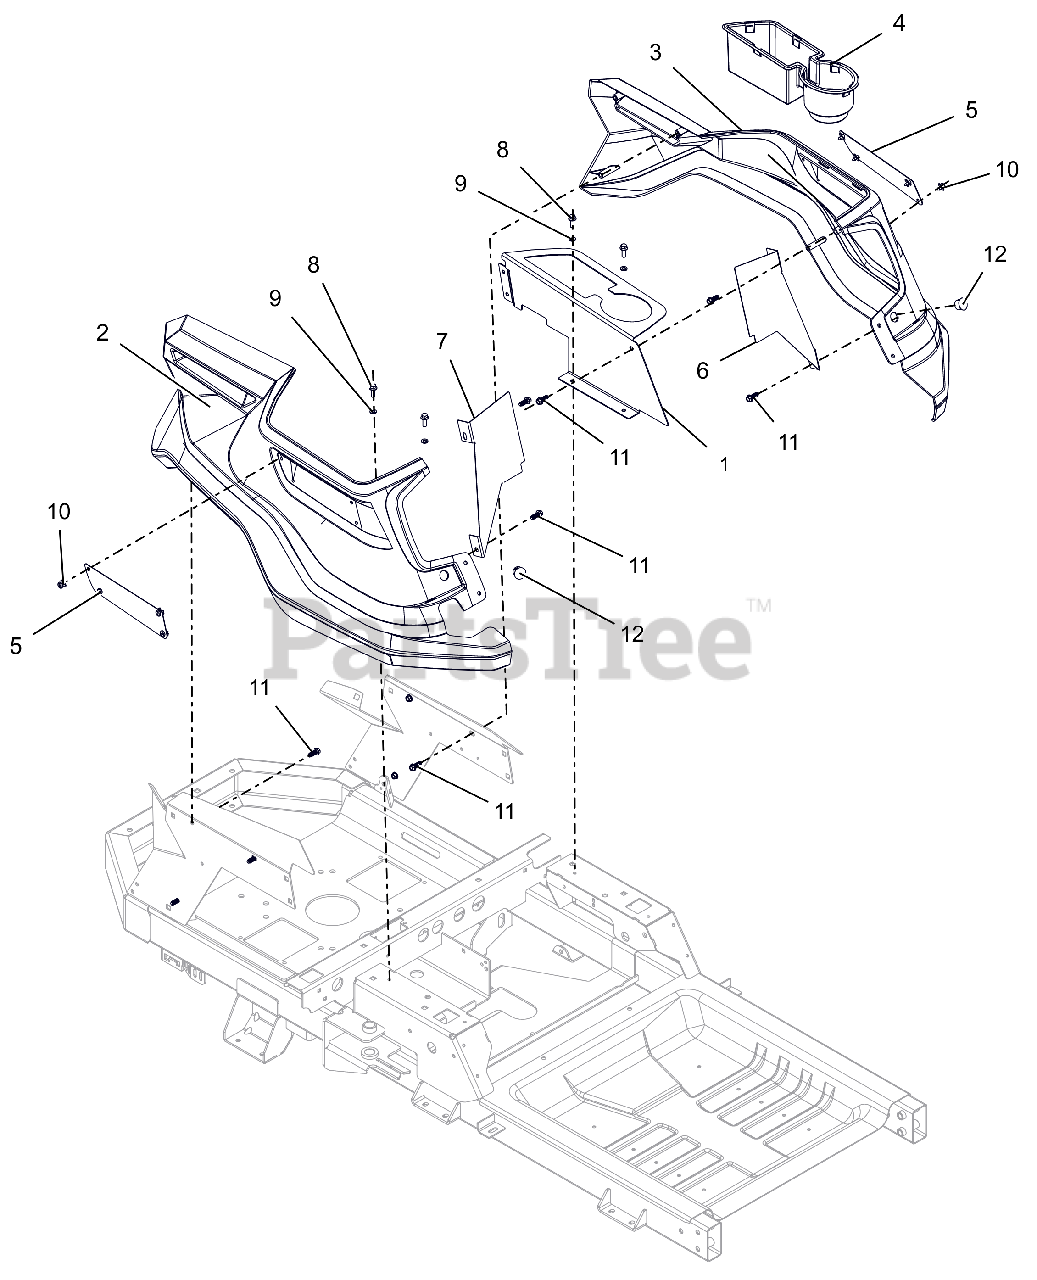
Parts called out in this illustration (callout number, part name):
1	PANEL, LEFT SIDE FENDER MOUNT
2	FENDER, RH IKON
3	FENDER, LH IKON
4	INSERT, CUP/STORAGE HOLDER
5	PLATE, ARIENS NAME
6	PLATE, LH BLOCKER
7	PLATE, RH BLOCKER
8	BLT,HEX-FLG .25-20X.75 G5 BFP
9	@WSHR-LK .25X.062 REG YWZC
10	RIVET, PLASTIC .195 DIA.
11	SCR-.312X.75 #14H H/W/H H/L CZ
12	PLUG, HOLE .75 (BLACK)
